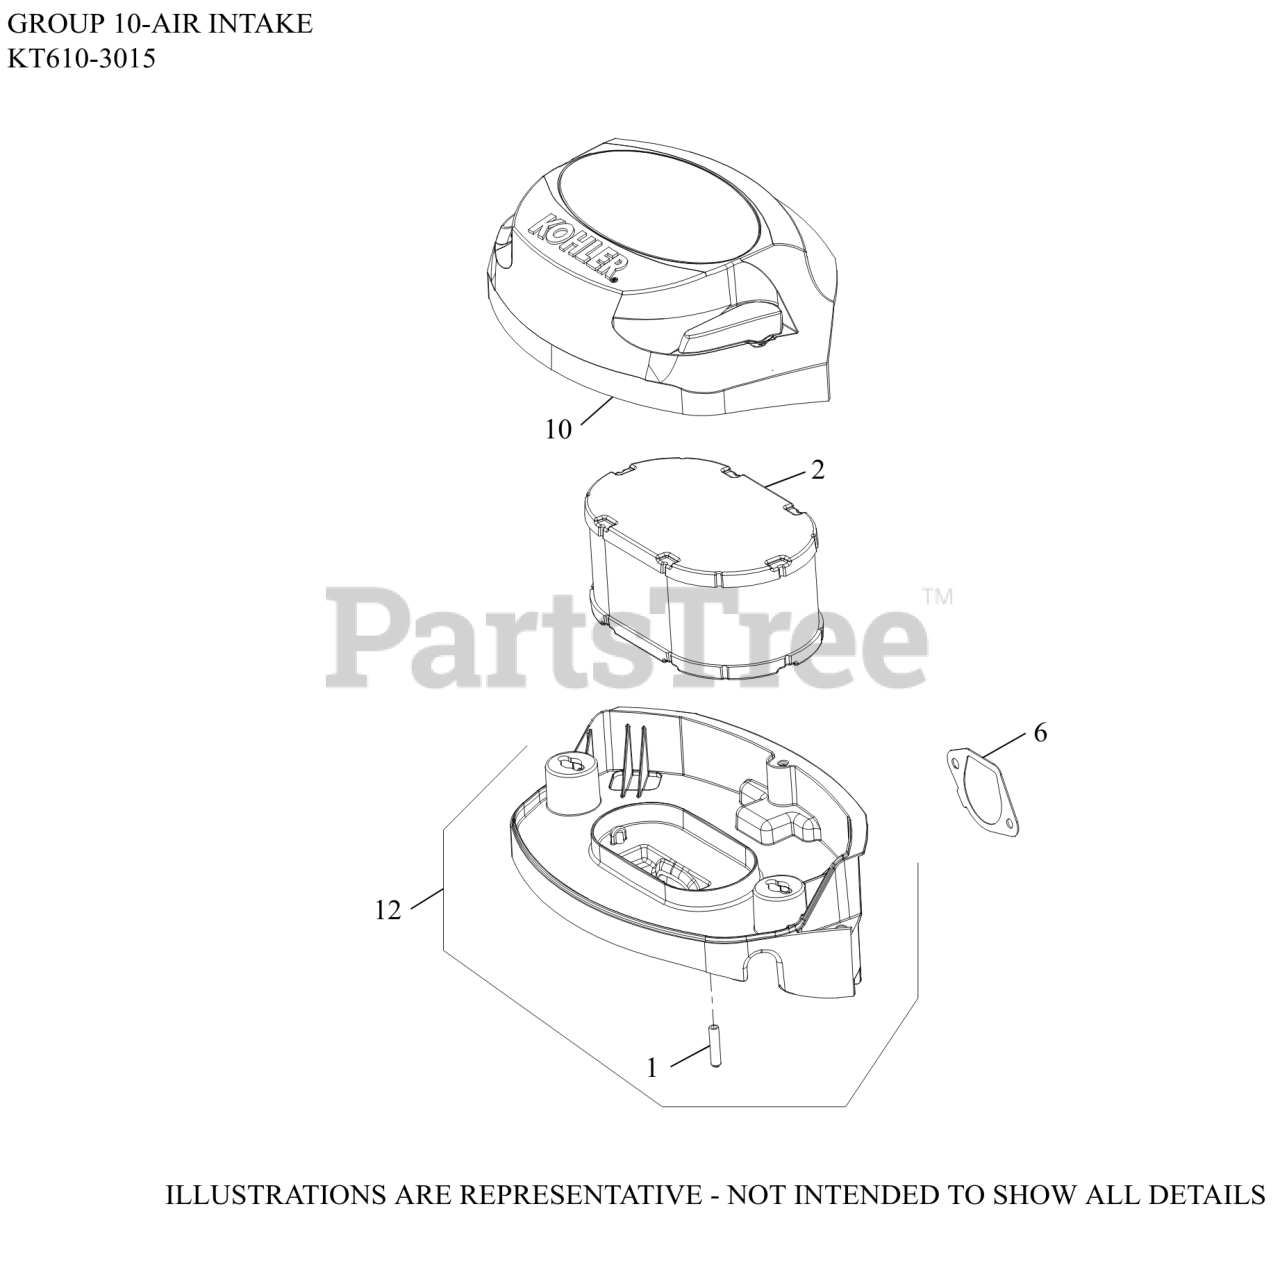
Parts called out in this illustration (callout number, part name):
1	CAP, MASKING
2	ELEMENT, AIR FILTER
6	GASKET, AIR CLEANER BASE
10	COVER ASSY, AIR CLEANER
12	BASE ASSY, AIR CLEANER
